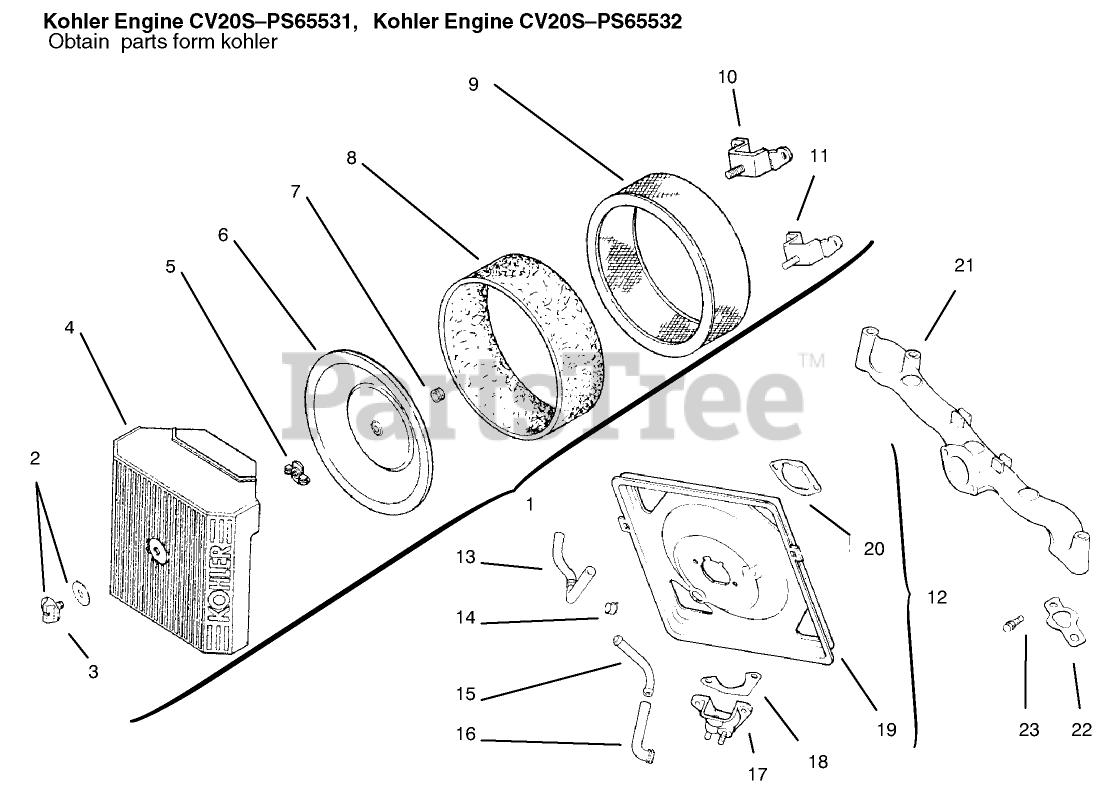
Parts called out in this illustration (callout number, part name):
1	Kit-A/C Cover INCL 2-4 (Only On: 72103;
2	Spring-Latch (Only On: 72103)
3	Latch-Lever (Only On: 72103)
4	Pin-Latch Lever (Only On: 72103)
5	Nut-Wing
6	Seal-Air Intake (Only On: 72103)
7	Cover-Inner Air Cleaner
8	Element-Precleaner
9	Element-Air Cleaner
10	Cup-Fuel Spitback (Only On: 72103)
11	Gasket-Fuel Spitback Cup (Only On: 72103, 72083)
12	Base-Air Cleaner (Only On: 72103)
13	Gasket-A/C Base (Only On: 72103, 72083)
14	Manifold-Intake (Only On: 72103)
15	Gasket-Intake Manifold
